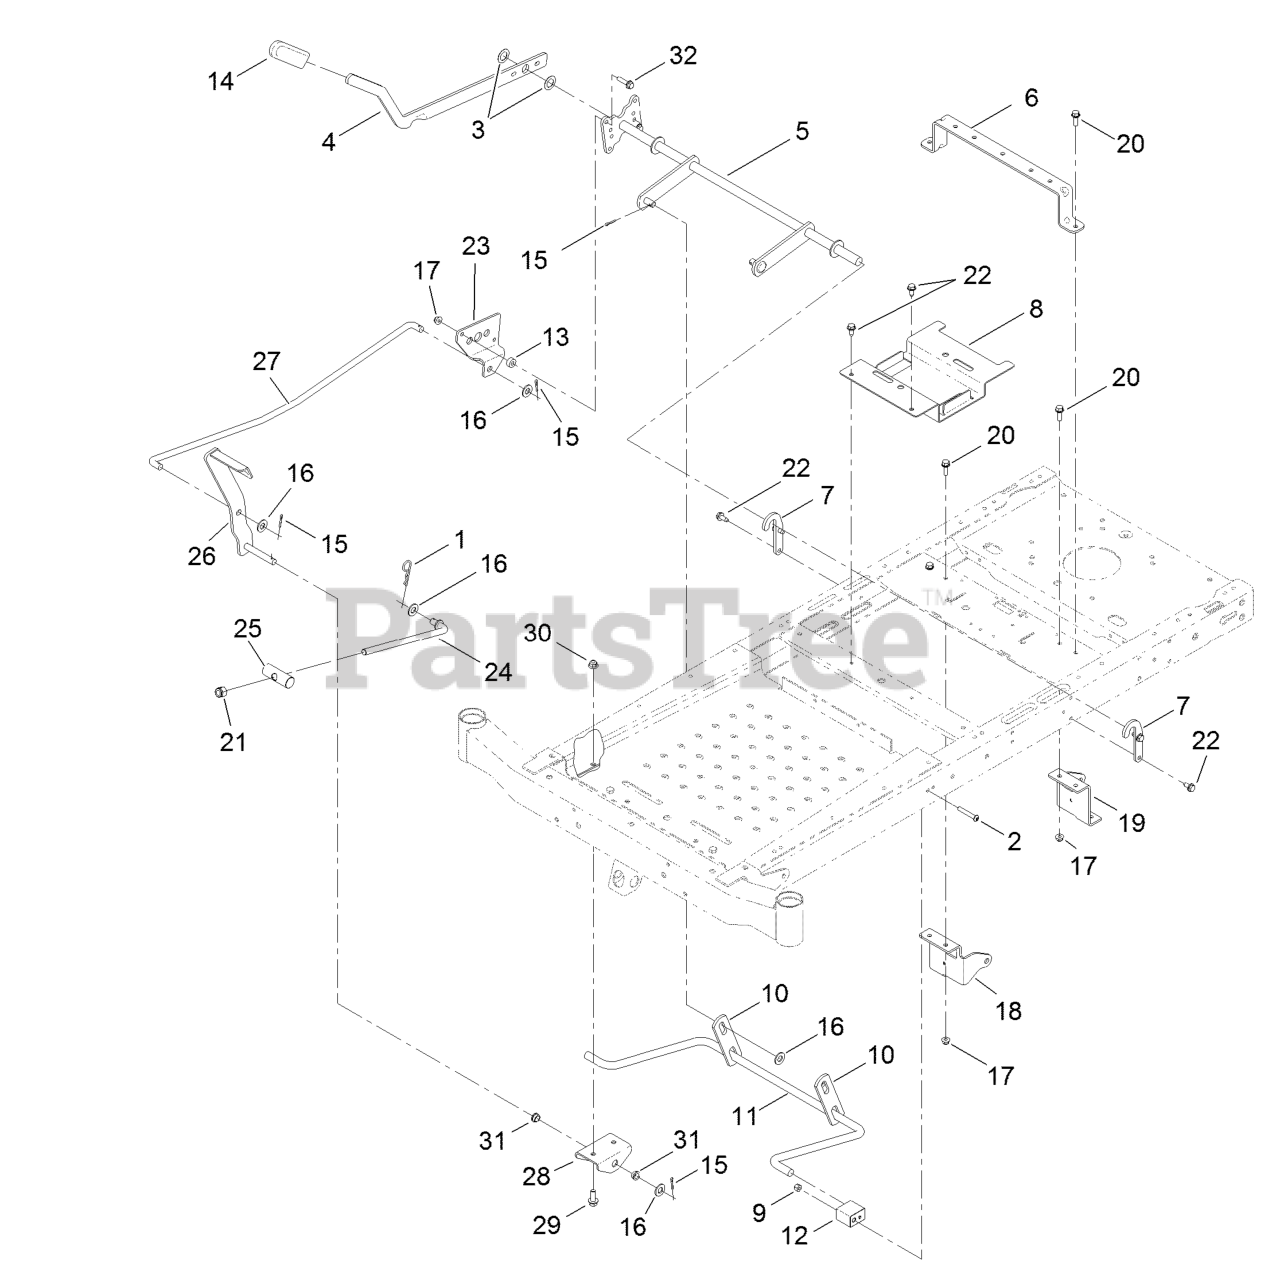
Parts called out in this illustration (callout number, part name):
1	PIN-COTTER
2	SCREW-HSBH
3	WASHER-THRUST
4	LEVER-LIFT
6	BRACE-SEAT, REAR
7	BRACKET-LIFT
8	BRACKET-BATTERY
9	NUT-LOCK, NI
10	LINK-LIFT
11	ARM-LIFT, REAR (WIDE)
12	BLOCK-PIVOT
14	GRIP-LEVER
15	PIN-COTTER
16	WASHER-FLAT
17	NUT-HF, NI
18	MOUNT-HYDRO, FRONT (RH)
20	SCREW-HHF
21	NUT-HEX
22	Screw-HWH 5/16-18 X 3/4 Tf
23	PLATE-FOOTLIFT
25	PIN-PIVOT
26	PEDAL ASM
27	ROD-FOOTLIFT
28	BRACKET-FOOTLIFT
29	SCREW-HHF 3/8-16 X 1
30	NUT-HF, NI
31	BUSHING-FLANGE
32	SCREW-HHF
